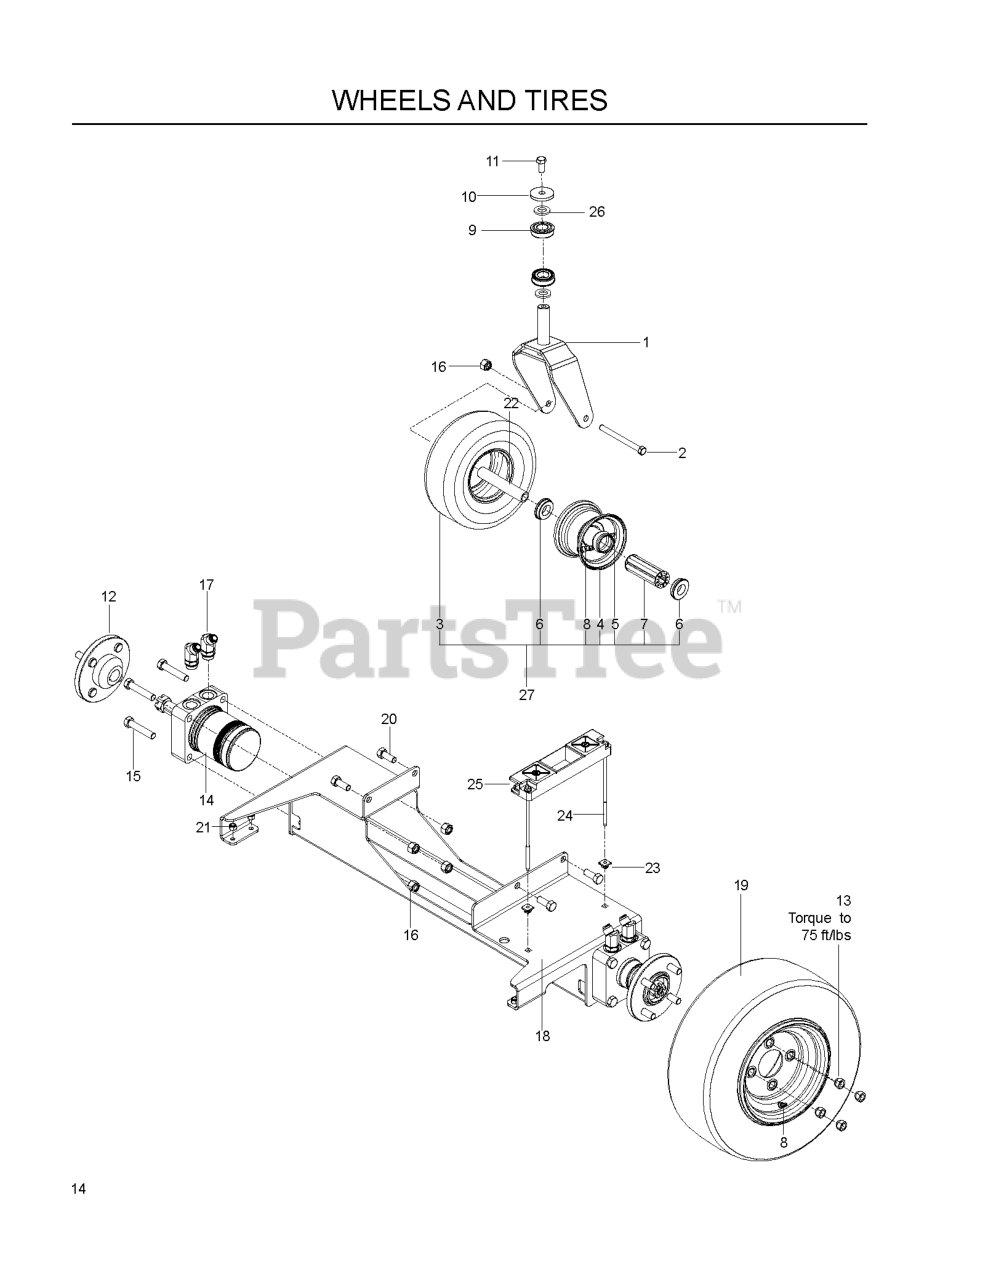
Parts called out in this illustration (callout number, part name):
1	PILLOW BLOCK
2	FRONT LIFT SHAFT
3	REINFORCEMENT BAR
4	HCS 5/16C X 2-3/4
5	NUT 5/16 NYLOC
6	LIFT SHAFT, REAR
7	STRUT LINKAGE
8	LIFT CHAIN - 3 LINK
9	NUT 7/16C CENTERLOCK
10	NUT 7/16C WHIZ
11	HCS 7/16C X 1 1/2
12	HEIGHT ADUST PLATE
13	DECK LIFT SPACER
14	SCREW 3/8C X 2 3/4 HEX CAP
15	HCS 3/8C X 2 1/4
16	HCS 3/8-16X1.GRD.5.ZD
17	NUT 3/8-16 NYLOC
18	HEIGHT ADJUST PLATE, OUTER
20	PAWL, STOP
22	HEX SCREW 1/2-13 X 2.5" GR 5
23	NUT 1/2-13 HEX NYLOC ZD
24	COTTER PIN
25	HAIRPIN #4
27	WASHER 1/2" FLAT
28	CROSS LINK
29	WASHER 5/8 FLAT
30	ANTI-SKID PAD
